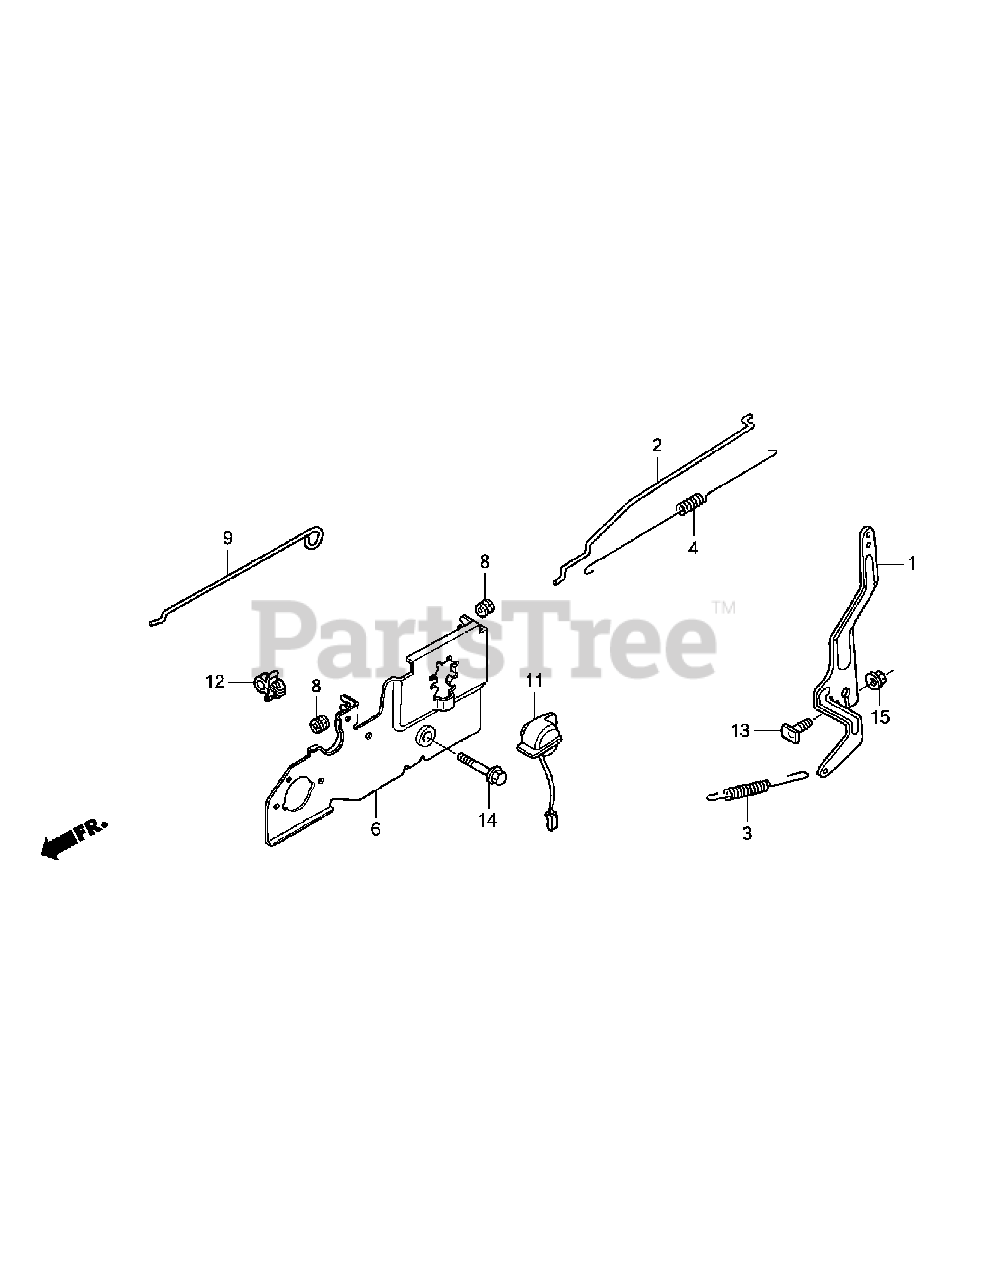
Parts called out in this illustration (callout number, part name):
1	Arm, Governor
2	Rod, Governor
3	Spring, Governor
4	Spring, Throttle Return
6	Base, Control
8	Grommet, Choke Rod
9	Rod, Choke
11	Switch Assy., Engine Stop
12	Holder, Wire
12	Clip A, Cable (Nifco)
13	Bolt, Governor Arm
14	Bolt, Flange (6x45)
15	Nut, Flange (6mm)
